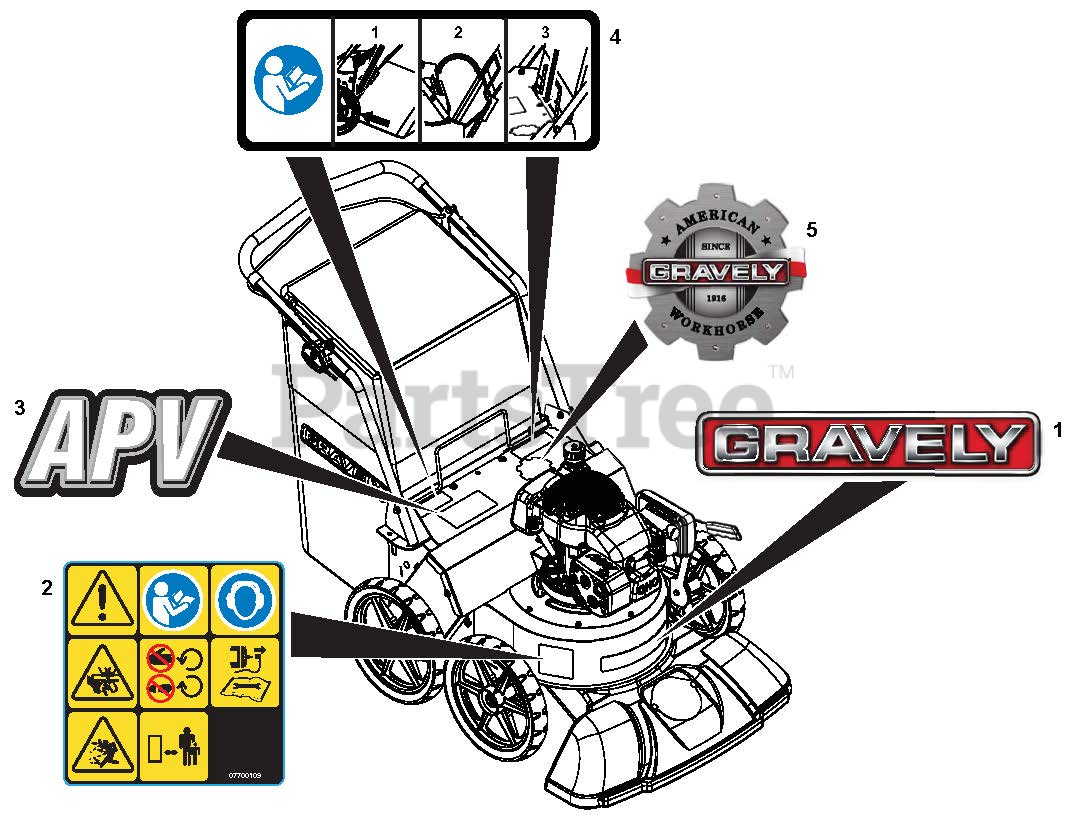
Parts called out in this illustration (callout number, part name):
1	DECAL, 9.5" GRAVELY LOGO
2	DECAL, WARNING -VAC ISO CE
3	DECAL, ACCESS APV
4	DECAL, BAG INSTRUCTIONAL-APV
5	DECAL, GRAVELY HERITAGE-LARGE
